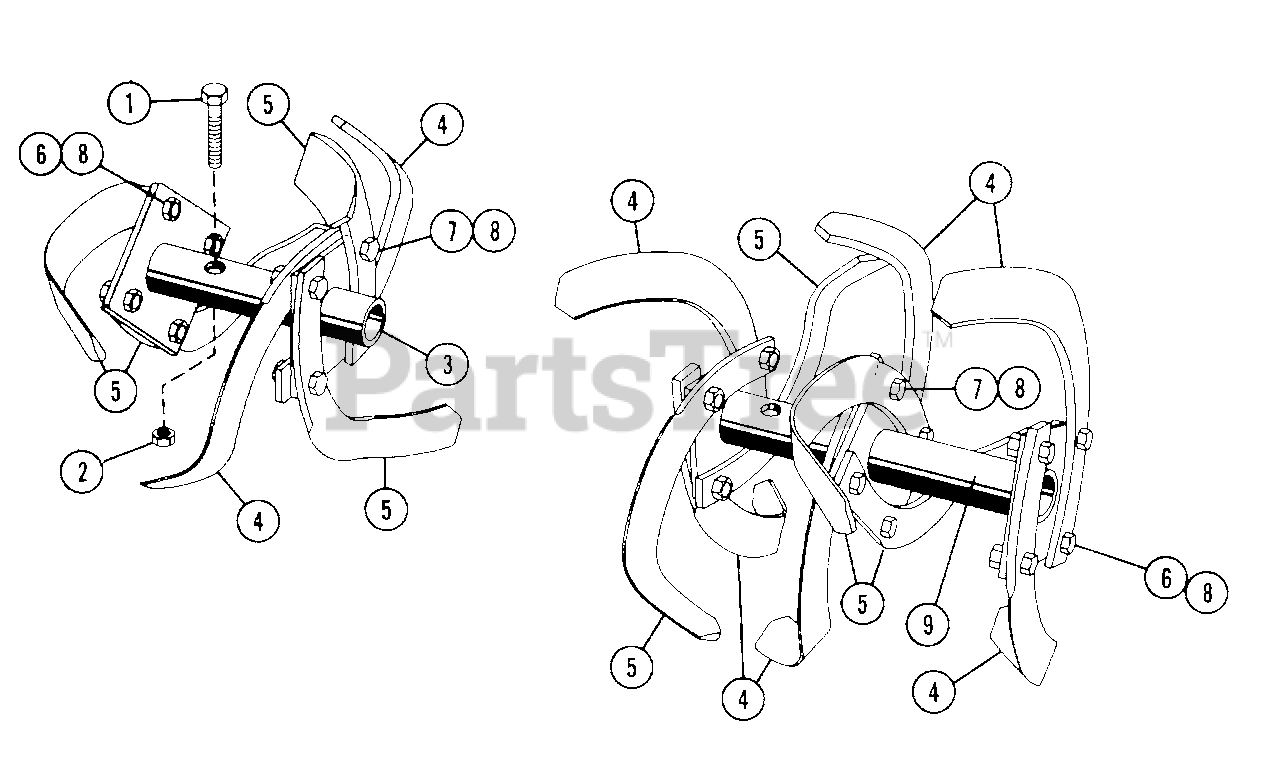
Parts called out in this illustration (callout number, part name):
1	BOLT, HEX 3/8-16X1.75
2	NUT, LOCK 3/8-16
3	SHORT TINE TUBE
4	TINE, L.H.
5	TINE, R.H.
6	BOLT, HEX 7/16-14X1
7	BOLT, HEX 7/16-14X1.50
8	NUT, LOCK 7/16-14
9	LONG TINE TUBE
